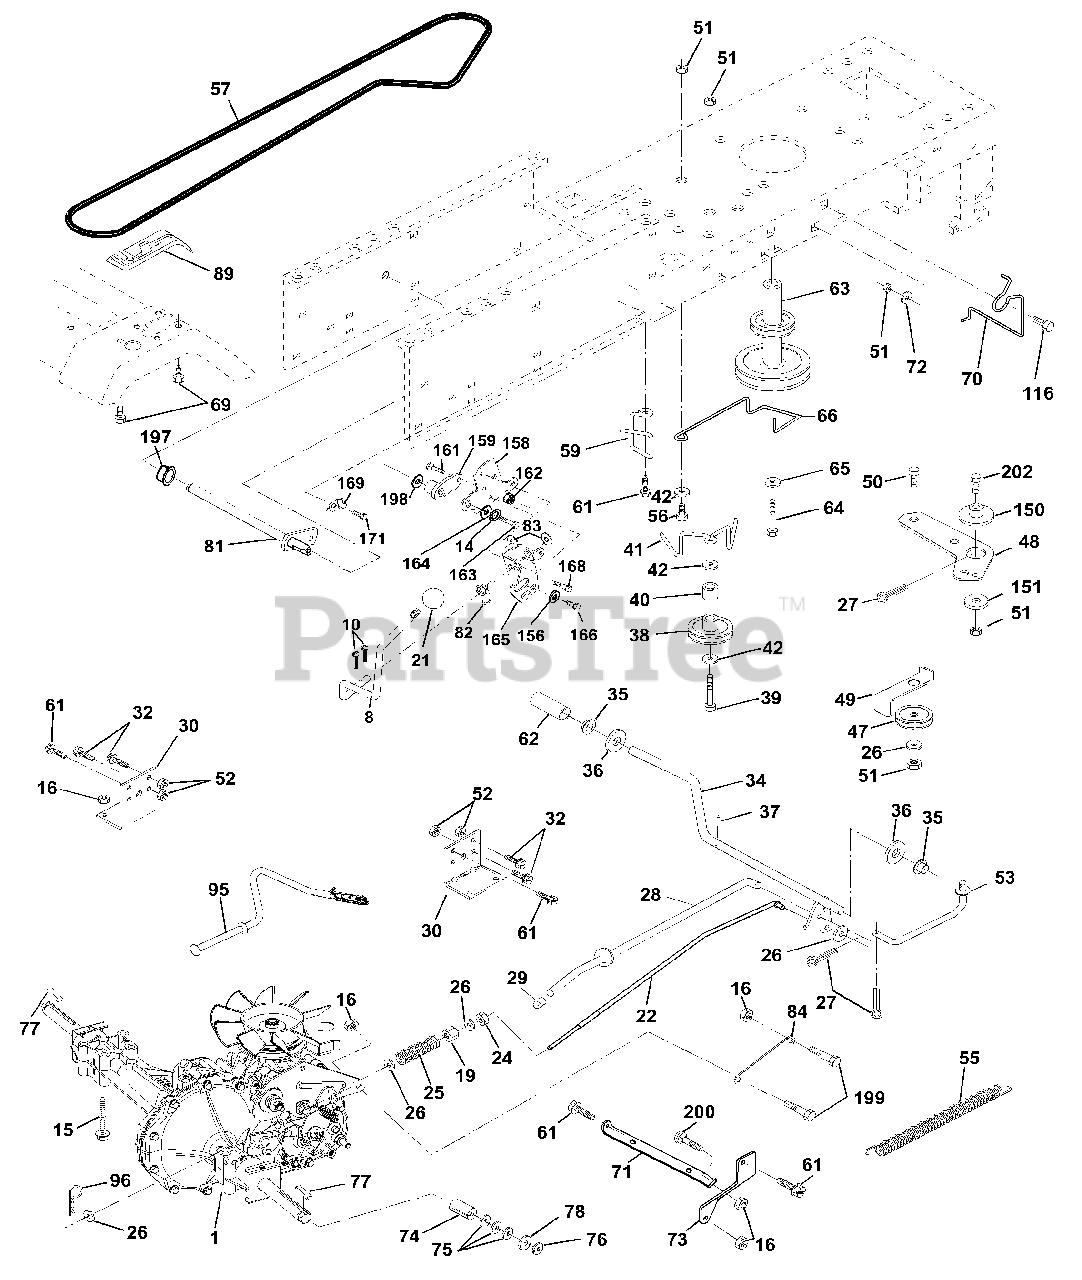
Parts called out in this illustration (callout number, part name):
8	Rod Shift Fender Adjust LT
10	Pin Cotter 1/8 x 1 CAD
14	Washer Lock Hvy Helical
15	Bolt, Hex FLGHD 5/16-18 Gr. 5
16	Nut Lock Hex W/Ins 5/16-18 Unc P
19	Nut Lock Hex W/Wsh 3/8-16 Unc
21	Knob, Round 1/2-13
22	Rod, Brake Hydro
24	Nut
25	Spring, Brake Rod
26	Washer
27	Pin Cotter 1/8 x 3/4 CAD.
28	Rod, Parking Brake
29	Cap, Parking Brake
30	Bracket, Transaxle
32	Bolt Hex Hd 5/16-18 Unc x 3/4
34	Shaft, Foot Pedal
35	Bearing, Nylon
36	Washer
37	Pin, Roll
38	Pulley, Idler, Flat
39	Bolt
40	Spacer, Split
41	Keeper, Belt Idler
42	Washer 13/32 x 13/16 x 12 Gauge
47	Pulley, Idler, V-Groove
48	Bellcrank Clutch Grd Drv Stl
49	Retainer, Belt
50	Bolt
51	Nut Crownlock 3/8-16 UNC
52	Nut Crownlock 5/16-18 UNC
53	Link, Clutch
55	Spring, Return, Clutch
56	Bolt Fin Hex 3/8-16 UNC x 1-1/4
57	V-Belt, Ground Drive
59	Keeper, Center Span
61	Screw 3/8-16 x 3/4
62	Cover, Pedal
63	Pulley, Engine
64	Bolt, Hex
65	Washer
66	Keeper Belt Engine Hydro
69	Screw
70	Keeper Belt Engine
71	Strap Torque Lh Hydro
72	Washer 13/32 x 1-1/4 x 12 Gauge
73	Strap Torque Rh Hydro
74	Spacer, Axle
75	Washer 25/32 x 1-1/4 x 16 Gauge
76	E-Ring
77	Key, Square
78	Washer 25/32 x 1-5/8 x 16 Gauge
81	Shaft Asm Cross Tapered
82	Spring Torsion T/A
83	Washer 17/32 x 3/4 x 16 Ga.
84	Link, Transaxle Hydro 0500
89	Console, Hydro
95	Control Asm Bypass Hydro
96	Retainer Spring 1" Zinc/Cad
116	Bolt Rdhd Sq Neck 3/8-16 x 1.25
150	Bushing Bellcrank Grd Drive
151	Washer 13/32 x 2 x 10 Ga.
156	Washer Srrted 5/16 ID x 1.125
158	Bracket Shift Mount
159	Hub Tapered Flange Shift LT
161	Bolt Rdhd Sqnk 1/4-20 x 3/4 Gr. 5
162	Nut Crownlock 1/4-20 Unc
163	Bolt Hex Fin 1/4-20 Unc x 1 Gr. 5
164	Washer 5/8 x .281 x 10 Ga.
165	Bracket Pivot Lever
166	Screw 5/16-18 x 5/8
168	Bolt Shoulder 5/16-18 x .561
169	Plate Fastening LT
171	Screw Thdrol 3/8-16 x 1/2 TY-TT
197	Nyliner Snap-In 5/8" Id
198	Washer Nyl 7/8 Id x .105
199	Bolt Shoulder 5/16-18 Unc
200	Bolt Rdhd Sqnk 5/16-18 Unc x 1
202	Bolt Carr Sh 3/8-16 x 1-1/2 Gr. 5
